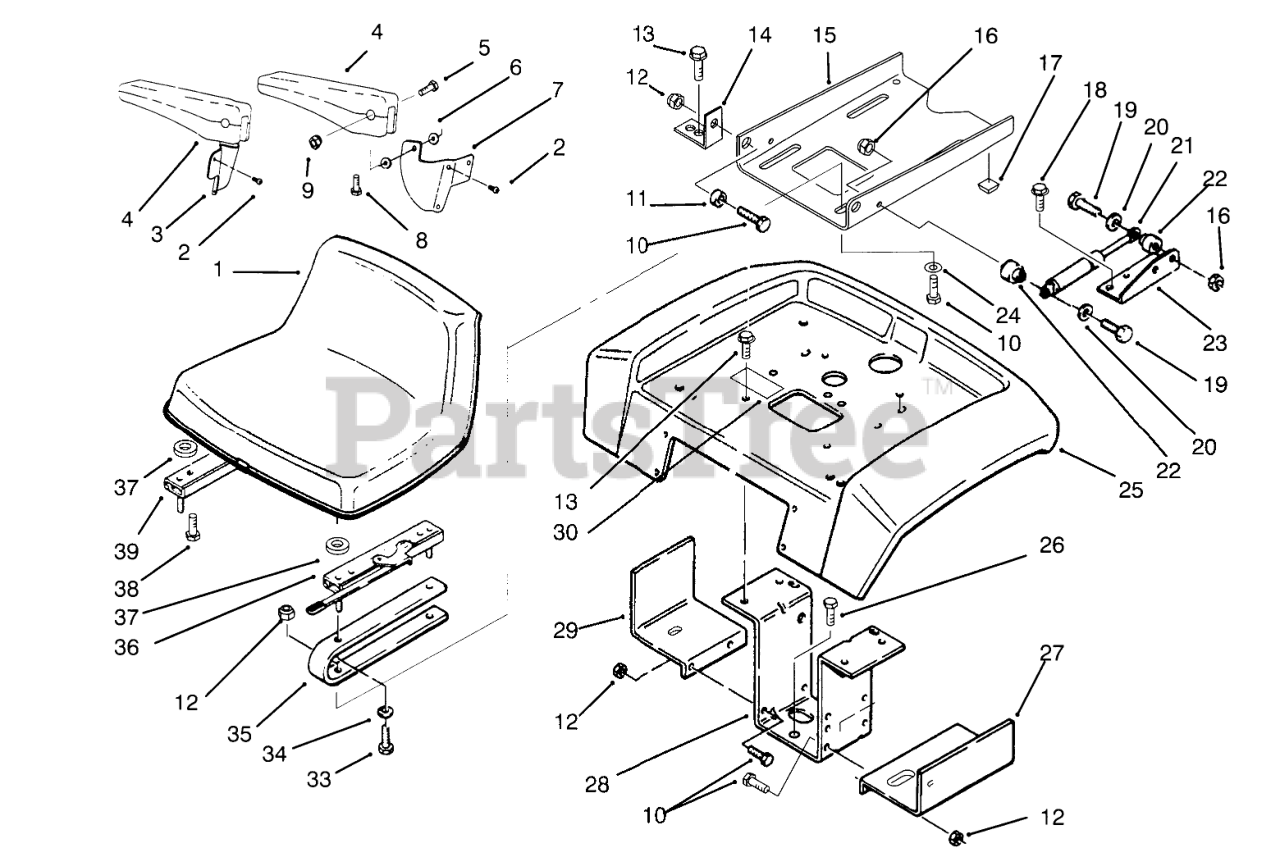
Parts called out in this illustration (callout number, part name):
1	Seat
2	3/8-16 X 5/8 SCREW
3	RH ARM BRACKET
4	ARMREST
5	3/8-16X1-1/2 SCREW
6	NYLON SPACER
7	LH ARM BRACKET
8	3/8-16 X 3/4 SCREW
9	3/8-16 ACORN LOCKNUT
10	SCREW-HH
11	BUSHING
12	NUT-LOCK, NI
13	Bolt
14	BRACKET-PIVOT
15	Plate-SeatPivot
16	NUT-LOCK, NI
17	BUMPER SJ5514 BLACK
18	Bolt
19	SCREW-HH
20	WASHER-FLAT
21	GAS SPRING
22	SPACER
23	BRACKET-CYLINDER R
24	WASHER-PLAIN
25	Fender
26	SCREW-HH
27	Fuel Tank Support LH
28	Bracket-Fender
29	Support-FueITank RH
30	DECAL-DO NOT TOW
33	SCREW-HH
34	WASHER-LOCK
35	Seat Spring
36	Adjuster-Seat
37	SPACER-NYLON
39	ADJUSTER-R.H. SEAT
